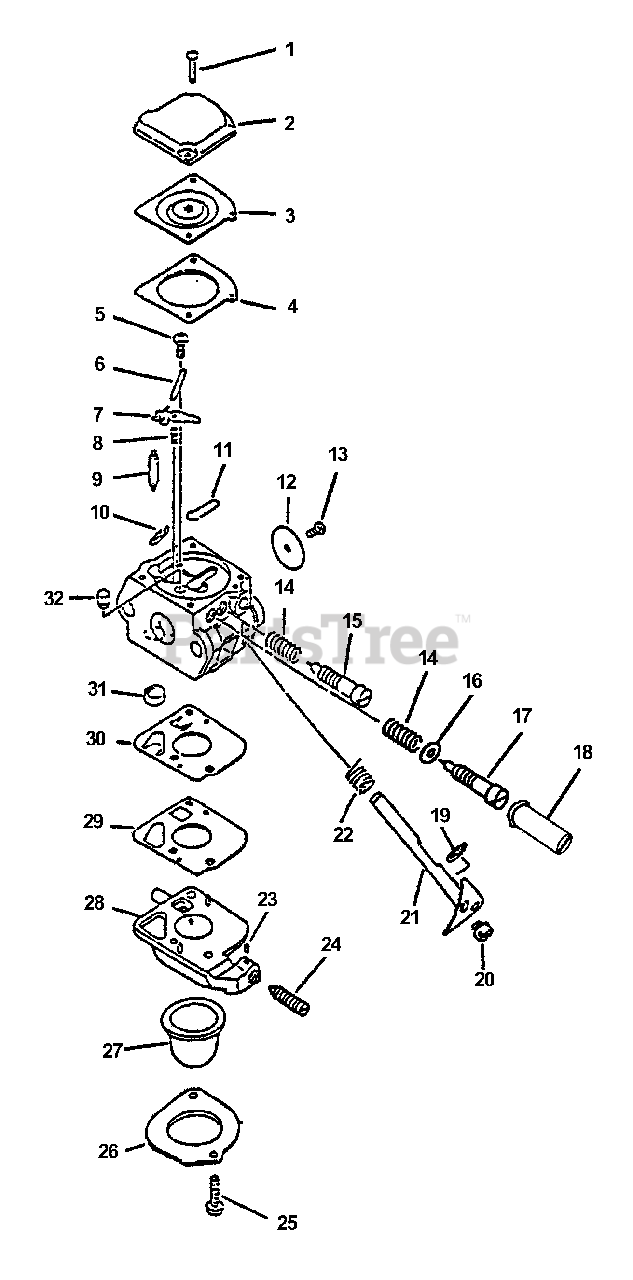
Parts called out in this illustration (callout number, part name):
2	COVER, METERING DIAPHRAGM
3	DIAPHRAGM
4	GASKET, METERING
5	SCREW, METERING LEVER PIN
6	PIN, METERING LEVER
7	LEVER, METERING
9	VALVE, NEEDLE
11	PLUG, WELCH
12	VALVE, THROTTLE
14	SPRING, NEEDLE
15	NEEDLE, IDLE
17	NEEDLE, HIGH SPEED
18	CAP, LIMITER
21	SHAFT, THROTTLE
22	SPRING, THROTTLE RETURN
23	PIECE, FRICTION
24	SCREW, IDLE ADJUST
26	RETAINER
27	BULB, PURGE
28	BODY ASSY, PURGE
31	STRAINER
32	NOZZLE, CHECK VALVE
